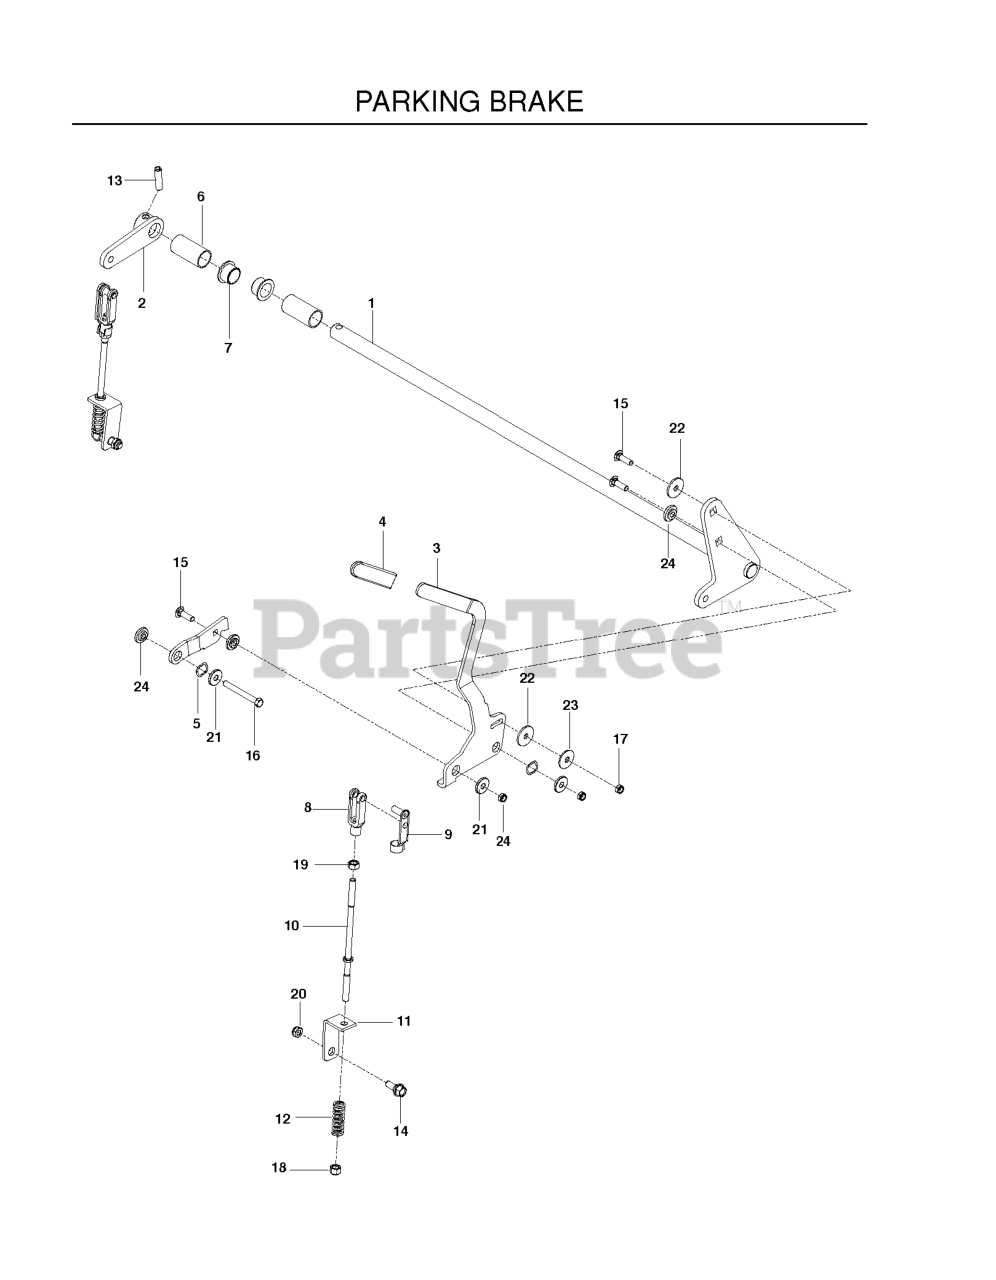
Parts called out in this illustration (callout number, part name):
1	SHAFT, BRAKE, WELDED
2	ARM, BRAKE, RT
3	LEVER.BRAKE.BLACK
5	LINK, FOLLOWER
6	SPACER, SHAFT, BRAKE
7	BEARING, FLANGE
8	YOKE 5/16 ADJ CLEVIS
9	PIN, CLEVIS SPRING, 3/8
10	LINKAGE, BRAKE
11	BRKT, BRAKE, BLK
12	SPRING, ENGAGEMENT
13	5/16 DIA ROLL PIN
14	BOLT, SHOULDER
15	RHSNB 3/8-16 X 1-1/4
16	HCS 3/8-16 X 3-1/4 GR5 ZD
17	NUT HEX 3/8-16 NYLON, THIN
18	NUT 5/16F NYLOC
20	5/16-18 THIN PROF NY
21	WASHER, .825 X 1.087, WAVE
22	WASHER, FRICTION, 1/8
23	CONE WASHER
24	BUSHING, BRAKE
